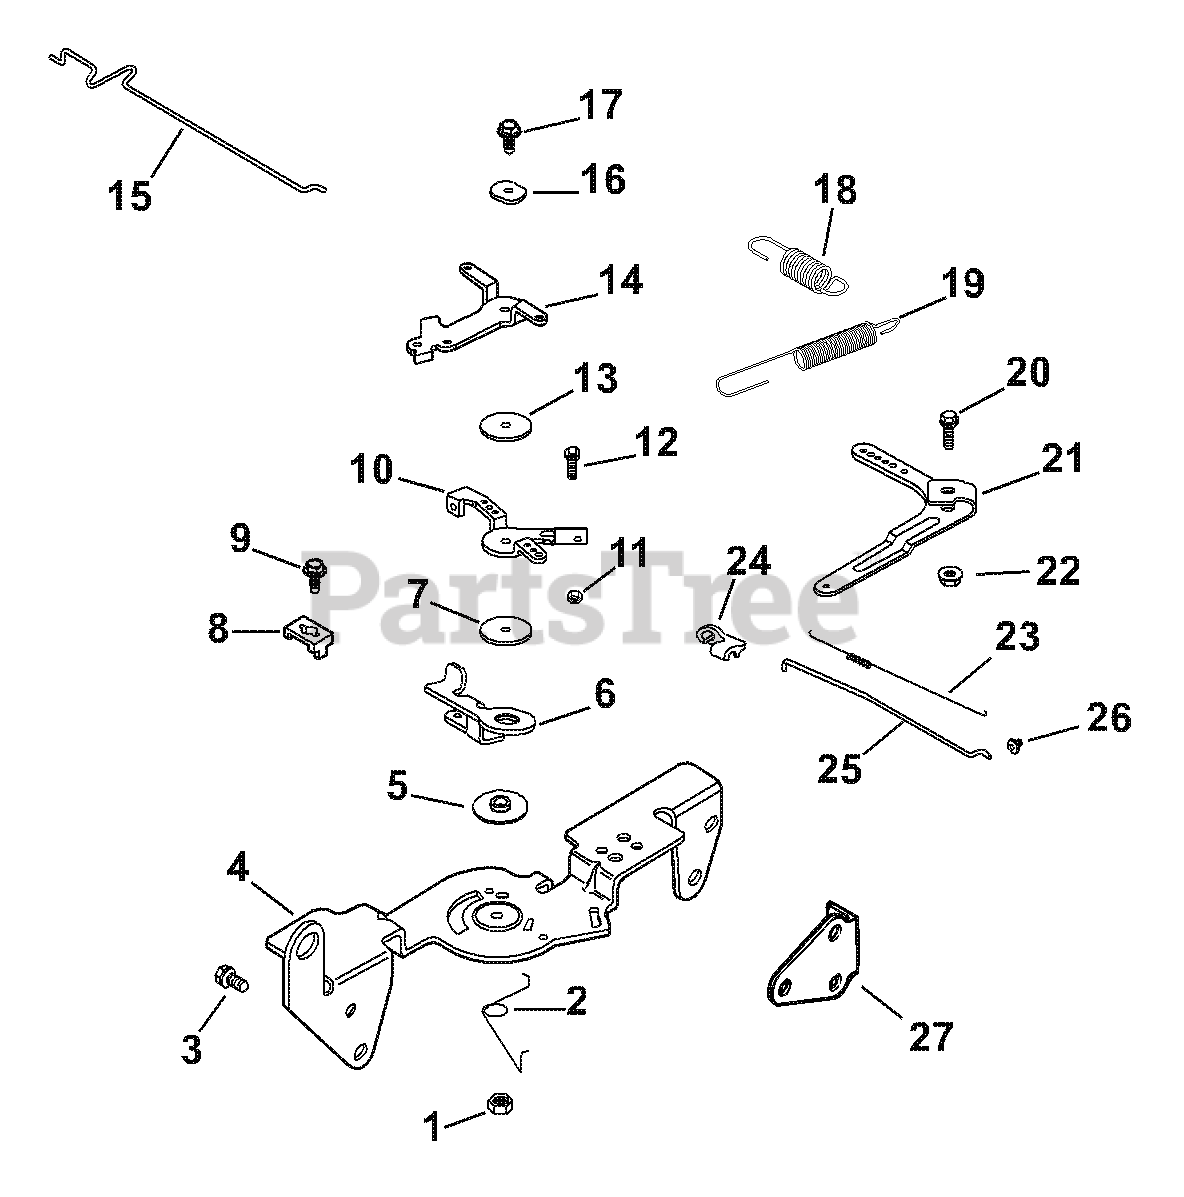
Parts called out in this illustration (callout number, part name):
1	Nut, hex. lock M5x0.8
2	Spring, choke return
3	Screw, hex. flange M6x1.0x16
4	Bracket, control
6	Lever, throttle actuator
7	Washer, plain
8	Clamp, cable
9	Screw, hex. flange M5x0.8x16
10	Lever, throttle control
11	Nut, hex M4x0.7
12	Screw, hex. cap M4x0.7x30
13	Washer, plain 5.5 mm
13	Linkage, choke
14	Lever, choke
16	Washer, spring 1/4"
17	Screw, hex. flange M5x0.8x20
18	Spring, governor
19	Spring, governor
20	Screw, hex. flange M6x1.0x25
21	Lever, governor
22	Nut, hex. flange M6x1.0
23	Spring, linkage
24	Bushing, linkage retaining
25	Linkage, throttle
26	Bushing, linkage retaining
27	Bracket, support
